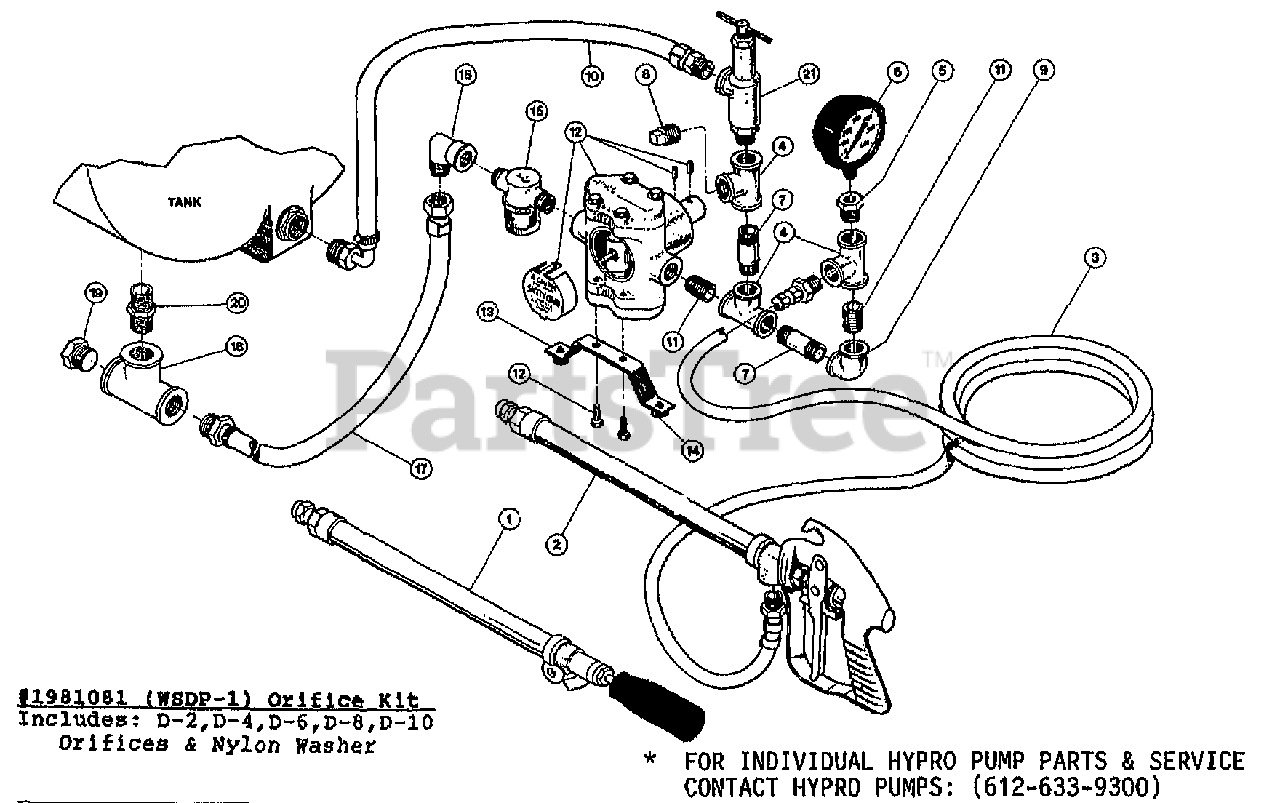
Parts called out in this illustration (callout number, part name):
1	GUN-TWIST SPRAY W143BR1/2
2	GRIP-PISTOL W43H6BR SPRAY GUN
3	HOSE-3/8 X 25' W2075660
4	TEE-1/2" PIPE W20983014
5	PIPE-BUSHING REDUCING
6	GAUGE-GLYCERINE PRESS WLFS220
7	NIPPLE-PIPE 50X2 GALVANIZED
8	PLUG-PIPE .50" W20984014
9	ELBOW-PIPE .50" W20986014
10	HOSE-RETURN LINE W2075603
11	NIPPLE-1/2" CLOSE W20981014
12	PUMP-TWIN PISTON
13	ARM-TRQ 25G SPRAY W28200028
14	BUMPER-RUBBER TORQUE ARM
15	STRAINER W33500079
16	ELBOW-1/2" STREET WSE12
17	HOSE-17" SUCTION W2075661
18	TEE-3/4 PIPE NYL WTT34
19	PLUG-3/4" PLASTIC WF3400
20	NIPPLE-3/4 CLOSE WM1400
21	VALVE PRESS.
